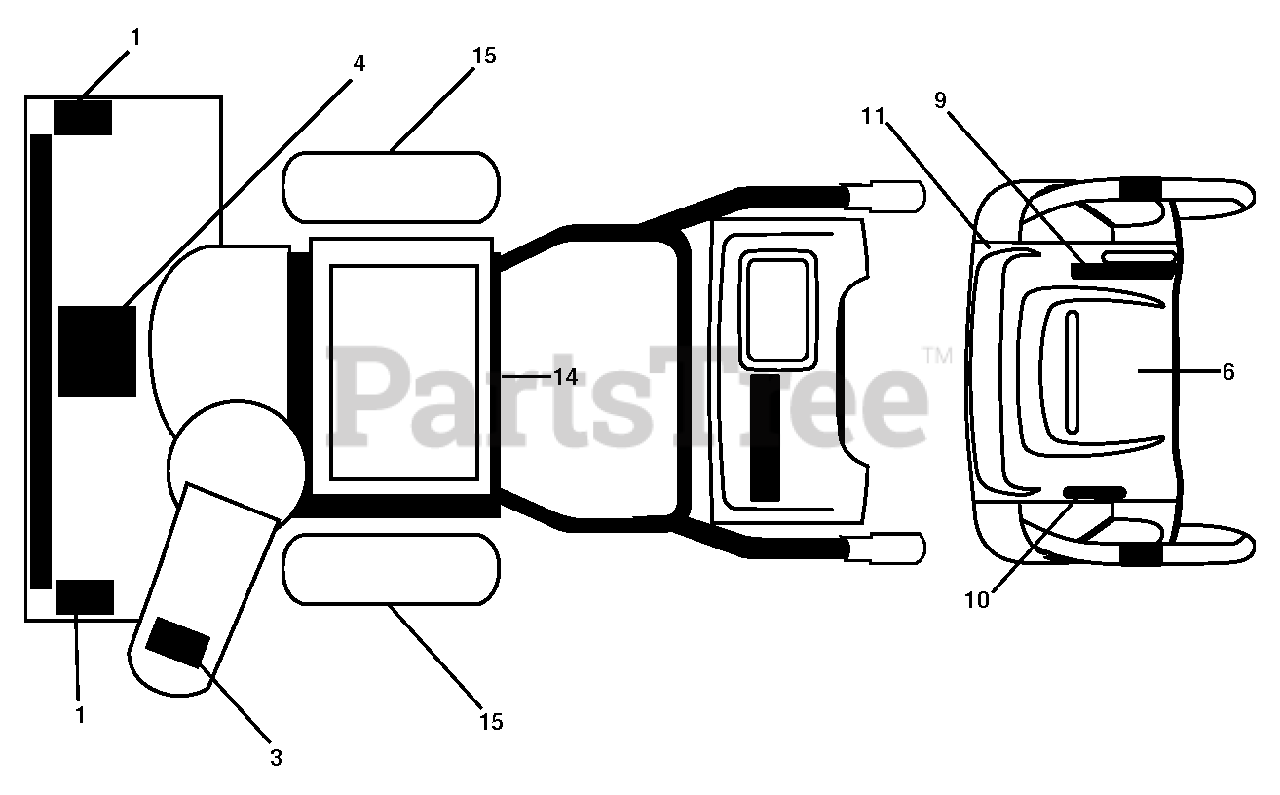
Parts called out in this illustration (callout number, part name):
1	DECAL.AUGER.SAFETY.
3	DECAL.CHUTE.SAFETY.
4	DECAL.AUGER."
9	DECAL.CONS.RT.SPD/LEV/PWRST.
10	DECAL.CONS.LT.SPD/LEV/PWRST.
11	DECAL.CONSOLE.HAND.WARMER
14	DECAL.FENDER
15	DECAL.BELT.GUARD.
